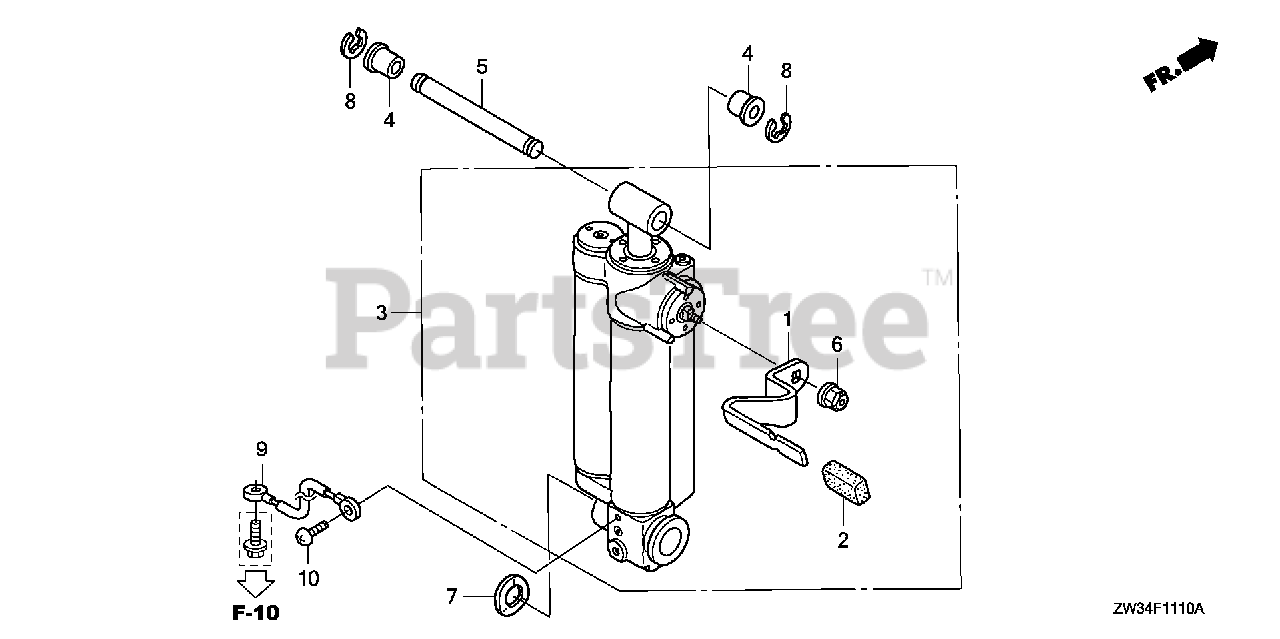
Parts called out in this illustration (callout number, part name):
1	LEVER, TILT
2	GRIP, TILT LEVER
3	SHOCK ABSORBER ASSY.
4	BUSH, CYLINDER (UPPER)
5	PIN, CYLINDER (UPPER)
6	NUT, SELF-LOCK (6MM)
7	WASHER, WAVE (26MM)
8	E-RING (10MM)
9	WIRE, LEAD (1.5X116MM)
10	SCREW, PAN (6X8)
